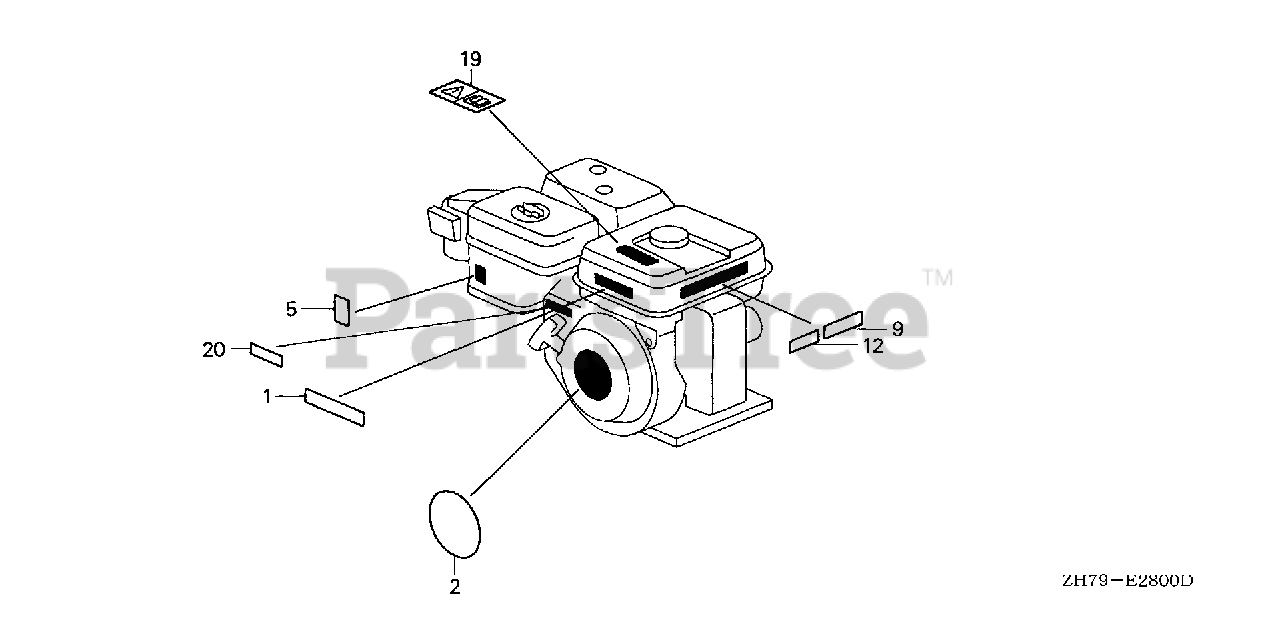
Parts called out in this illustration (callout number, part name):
1	LABEL, CAUTION
2	EMBLEM
5	MARK, CHOKE
